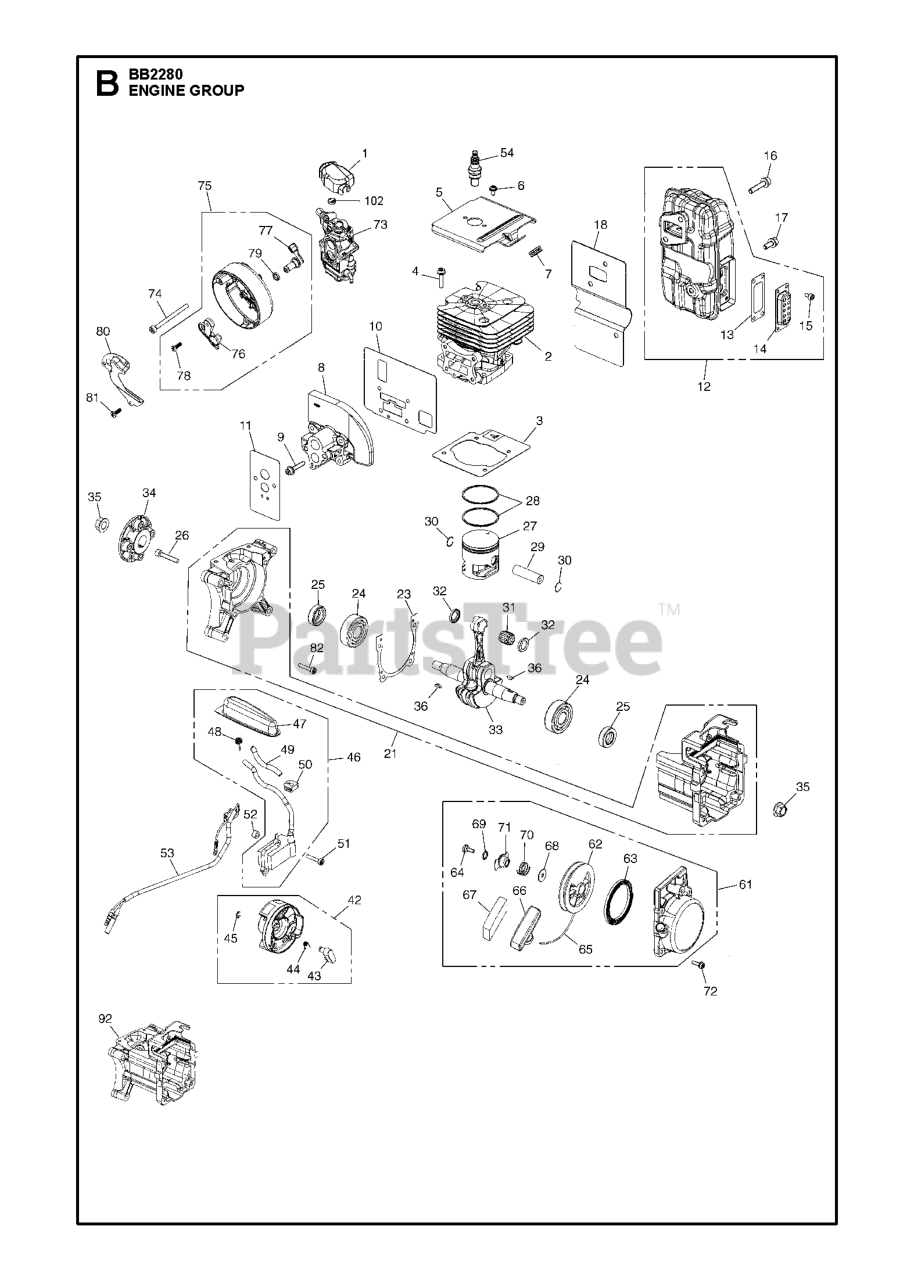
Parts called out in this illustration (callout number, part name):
2	CYLINDER ASSY
3	GASKET
4	BOLT
8	INSULATOR
10	GASKET
11	GASKET
12	MUFFLER ASSY
13	SPARK ARRESTER
15	BOLT
18	INSULATOR
21	CRANKCASE COMP
23	GASKET
24	BALL BEARING
25	SEAL
28	RISTON RING
29	PISTON PIN
30	SNAP RING
31	BEARING
33	CRANKSHAFT COMP
36	KEY
42	Rotor Assembly
43	RATCHET
44	SPRING
45	RING
46	Ignition Coil Assembly
47	CAP
48	SPRING PLUG
49	TUBE
50	GROMMET
52	SPACER
61	RECOIL ASSY
62	REEL
63	SPRING
64	SCREW
65	ROPE
66	KNOB
67	COVER
68	WASHER
69	WASHER
70	SPRING FRICTION
71	PLATE
73	Carburetor Assembly
76	PLATE CHOKE
77	LEVER
79	O-Ring
80	PLATE
81	SCREW
92	CRANKCASE ASSY
